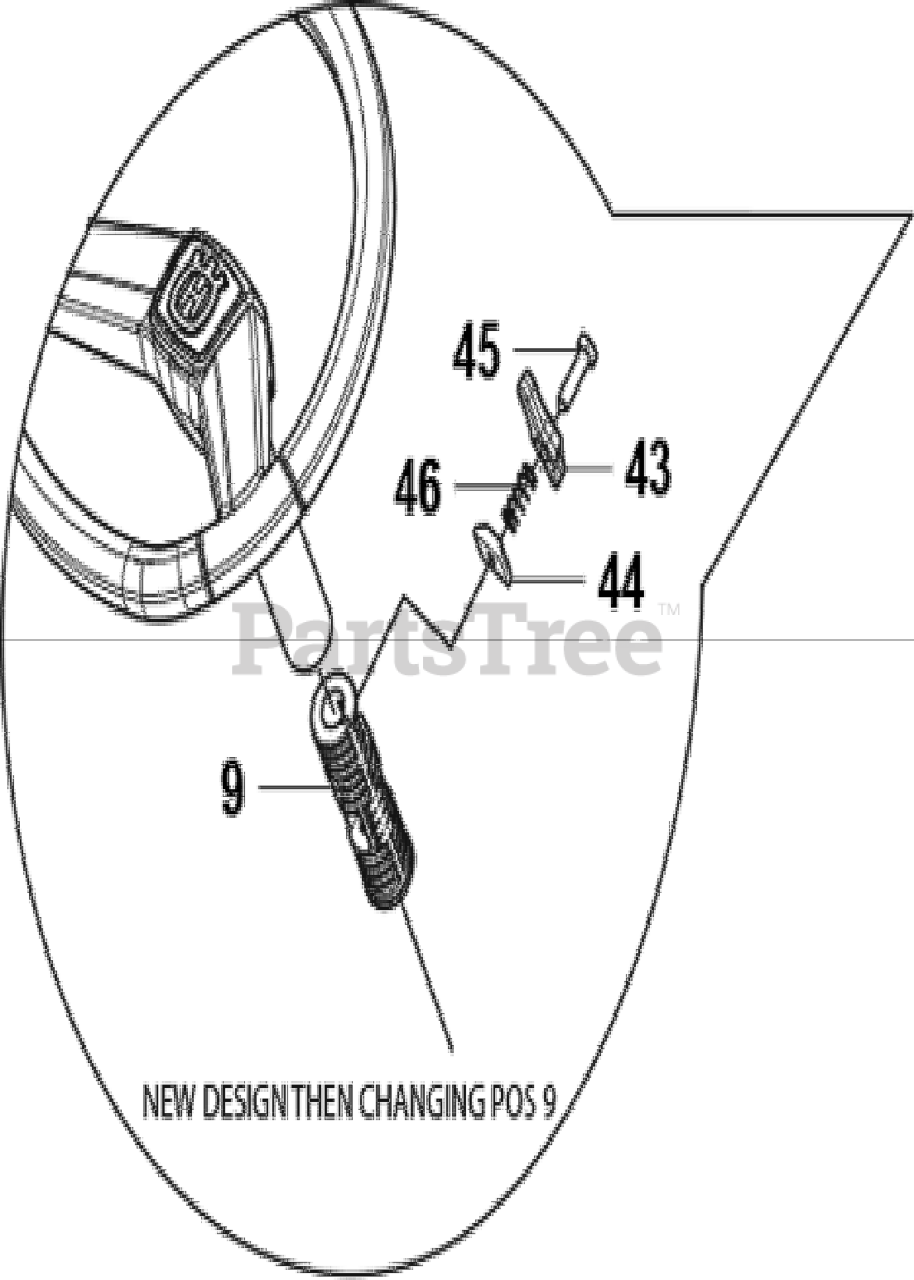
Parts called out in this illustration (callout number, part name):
2	SPRING BRACKET
5	STEERING WHEEL
7	NUT
8	STEERING ROD ASSY LONG
9	SPACER
11	BRACKET STEERING ASSY WITH BUS
20	COLLAR SCREW
22	WIRE ASSY
24	SHAFT
25	RETAINING RING
26	STEERING CHAIN
28	WIRE GUIDE
31	Ball Bearing 6005-2rs
32	BALL BEARING 6010 2RS1
33	CIRCLIP SGH 47
34	RETAINING RING SGA 25
36	RETAINING RING SGA 25
39	NUT
40	BRACKET STEERING ROD ASSY
41	RETAINING RING SGA 15
42	PROTECTIVE COVER
43	HANDLE
44	FIXING PLATE
45	PIN
46	SPRING STEERING ADJUSTMENT
